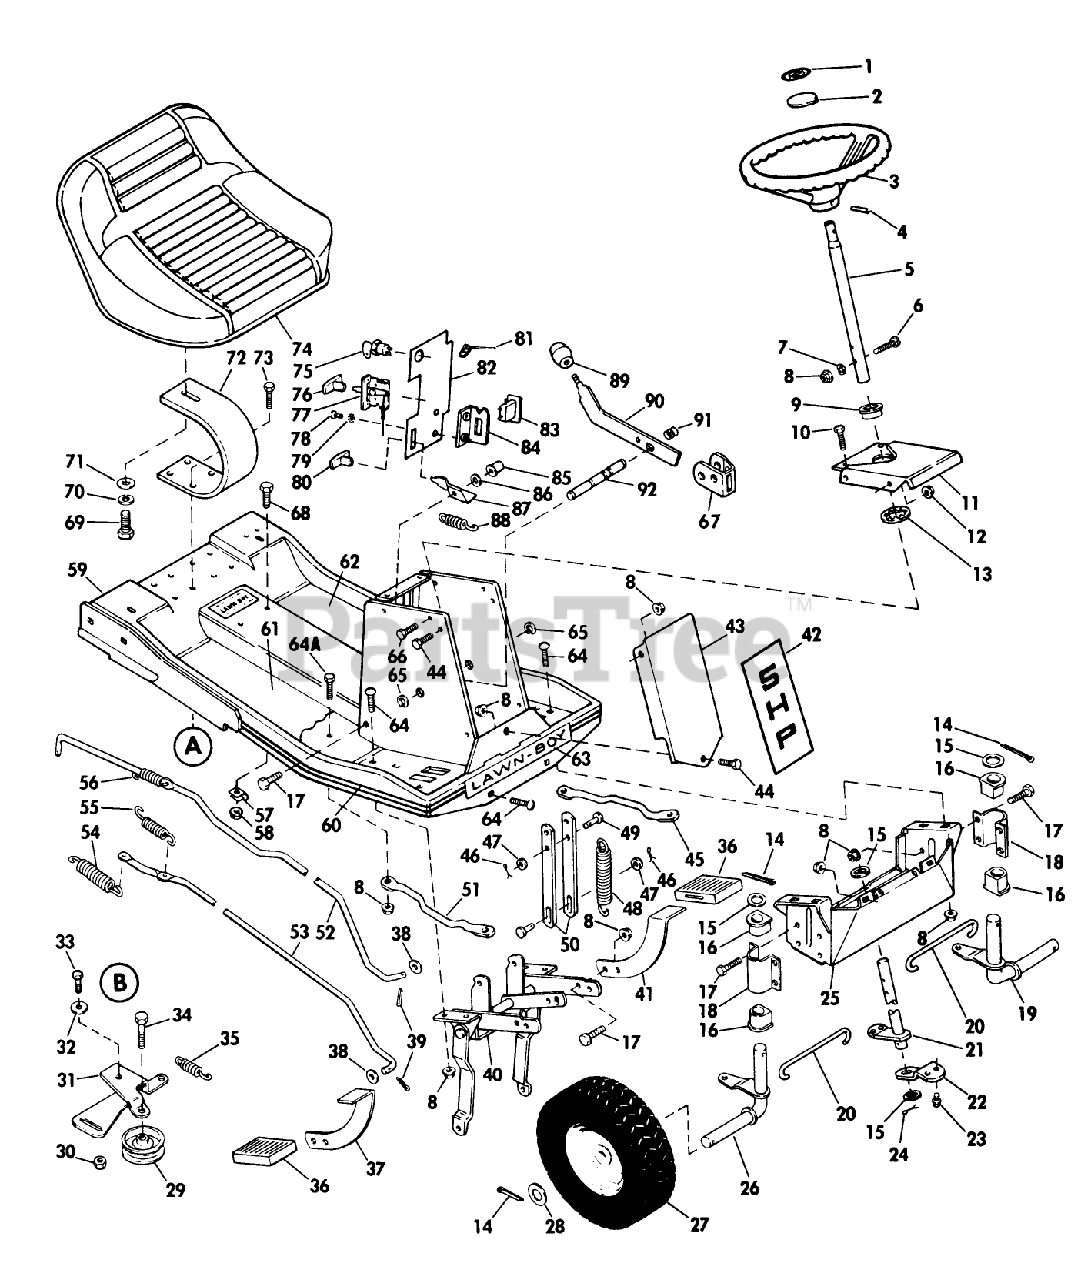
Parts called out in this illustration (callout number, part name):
1	Decal-Steering Wheel
2	Cap-Steering Wheel
3	Steering Wheel
4	Pin-Roll-Steering Wheel
5	Steering Column
6	Screw-Engine Mounting
8	NUT
9	Bushing
11	Top Panel-Control Panel
12	Nut-Top Panel
13	Retaining Ring-Steering Column Bushing
14	Cotter Pin
15	Washer-Front Axle
16	Bushing-Front Axle
18	Bracket-Front Axle
19	Axle Assembly-Front L.H.
20	Tie Rod
21	Steering Shaft Assembly
22	Bearing-Lower Steering Shaft
23	Screw-Bearing-Lower Steering Shaft
25	Frame-Front Axle Mounting
26	Axle Assembly-Front R.H.
27	Wheel and Tire Assembly-Front
28	Washer-Wheel and Tire Assembly
29	Pulley-Idler
31	Idler Lever
32	Washer-Spring-Packing Brake Pivot
33	Screw
34	Screw
35	Spring
36	Pad-Foot Pedal
37	Pedal-Foot R.H.
39	Pin
40	Control Shaft Assembly
41	Pedal-Foot L.H.
42	Decal-5 H.P.
43	Front Panel-Control Console
45	Rod-Support Front Axle to Frame L.H.
48	Spring-Tie Bar-Blade Clutch
49	Clevis Pin
50	Tie Bar-Clutch Blade
51	Rod-Support Front Axle to Frame L.H.
52	Brake Rod
53	Clutch Rod
54	Spring-Clutch Rod
55	Spring
56	Spring-Brake Rod
57	Clamp-Wire Harness (Manual Start Only)
58	Nut-Wire Harness Clamp
59	Front Frame Member
60	Decal Side Strip
61	Mat-Floor-R.H.
62	Mat-Floor-L.H.
64	Bolt
64A	Bolt
65	E-RING
67	Guide-Blade Clutch Shaft
71	Washer-Seal Support
72	Seal Support
73	Screw-Seat Support
75	Switch and Key Assembly
76	Handle-Throttle Control
77	Throttle Control Assembly
78	SCREW F
79	Lockwasher
80	Handle-Parking Brake
81	Cable-Ground
82	Decal-Control Panel
83	Switch-Blade Control
84	Bracket-Switch-Blade Control
85	Well Nut-Parking Brake Latch
86	Washer-Spring-Packing Brake Pivot
87	Latch-Parking Brake
88	Spring-Parking Brake
89	Knob-Blade-Clutch Control
90	Handle-Clutch Blade
91	Spring-Blade-Clutch Shaft
92	Shaft-Blade Clutch
